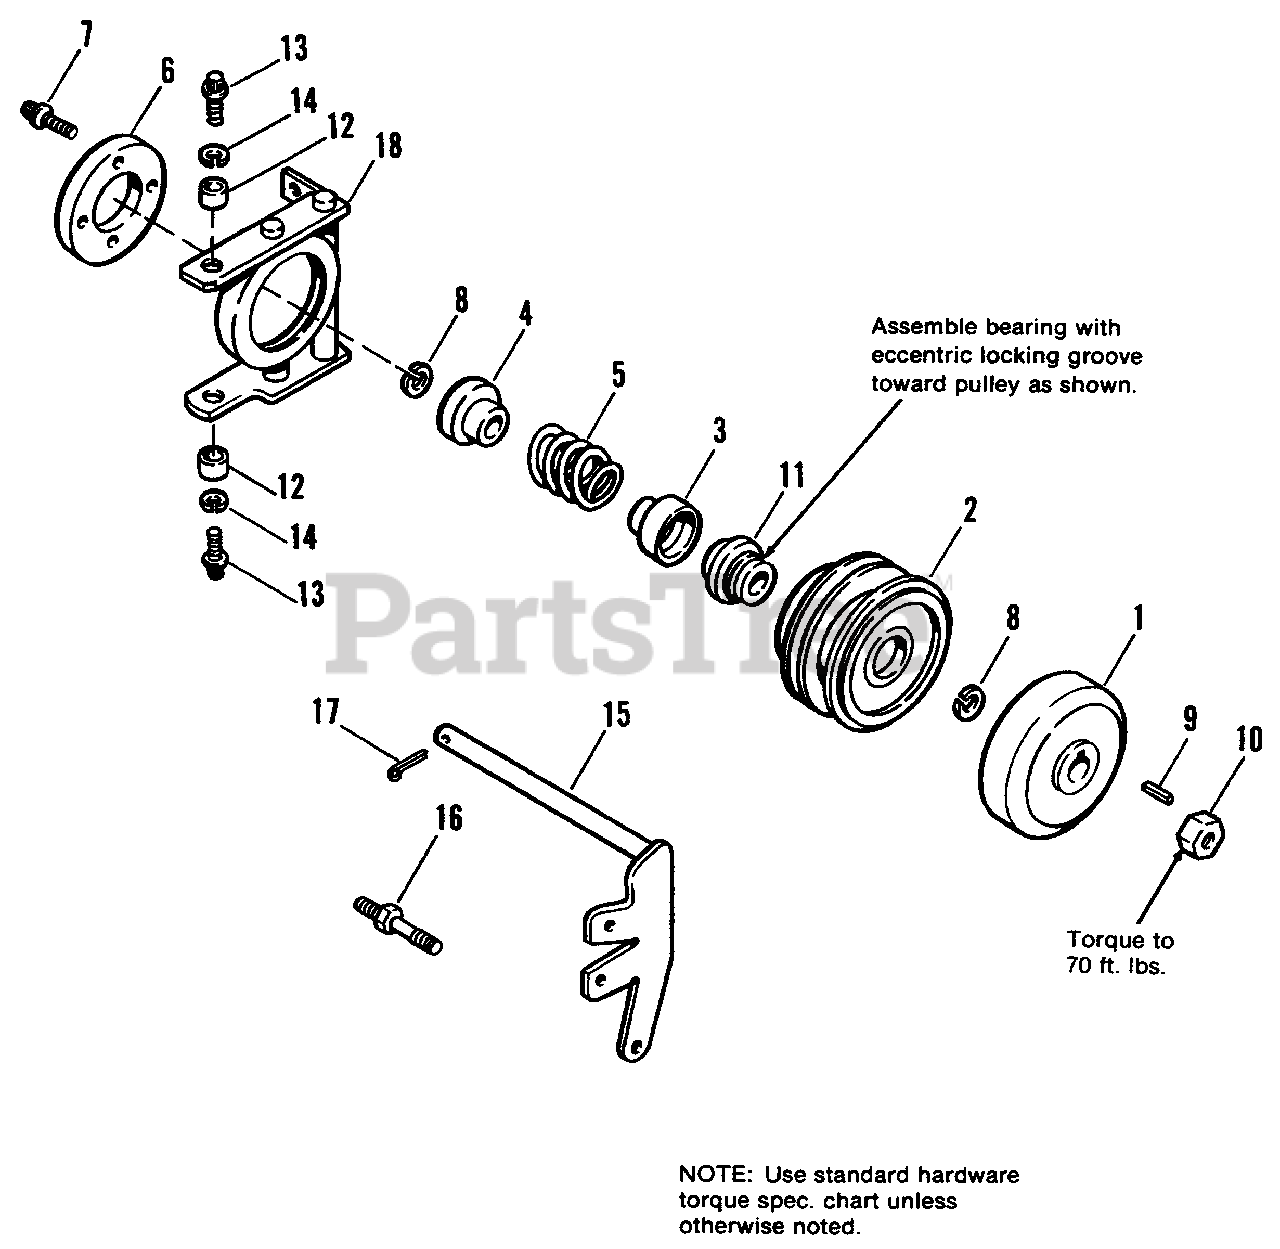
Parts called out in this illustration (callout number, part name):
1	CLUTCH PLATE ASSY.
3	GUIDE, Spring, Outside
4	GUIDE, Spring, Inside
6	DISC, Brake
7	CAPSCREW, Skt. Hd., 1/4-20 x 5/8
8	RING, Retaining
9	KEY
10	LOCKNUT, Hex, 3/4 x 16
11	BEARING ASSY.
13	SCREW, Thd. Forming
14	LOCKWASHER, 5/16
15	PIVOT ARM ASSY.
17	PIN, Cotter, 3/16 x 1-1/2
18	PIVOT ASSY.
